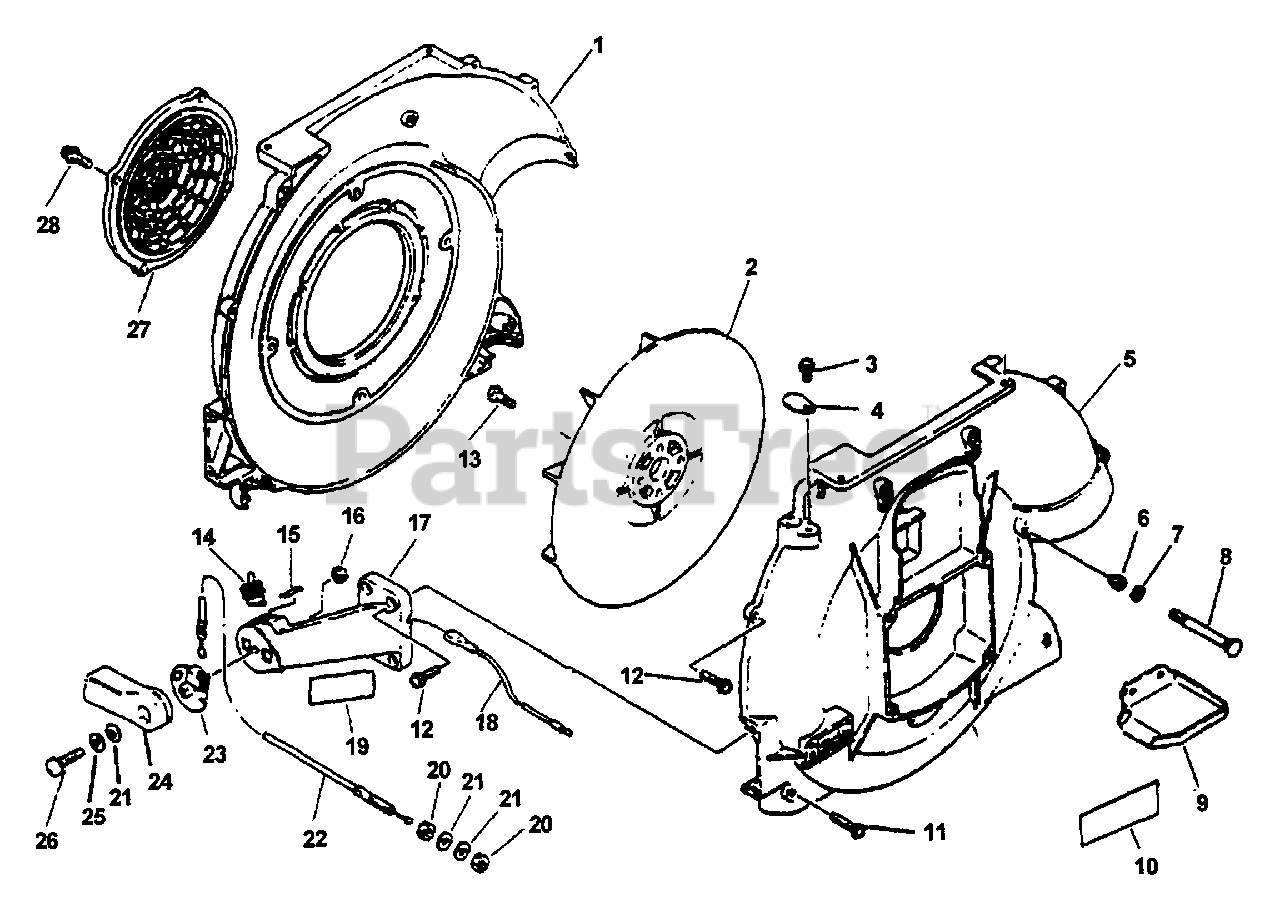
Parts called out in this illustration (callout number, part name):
1	COVER, FAN - INNER -- ORANGE
3	SCREW - 5X10
5	COVER, FAN - OUTER
6	NUT - 5 -- CAP
7	WASHER - 5
8	BOLT, ELBOW
9	BRACKET, MUFFLER COVER
10	LABEL - NOISE
11	SCREW - 5X25
12	SCREW - 5X20
13	BOLT - 5X16
14	IGNITION SWITCH ASSY
15	LABEL - STOP
16	LOCKNUT - 6
17	MOUNT, THROTTLE LEVER
19	LABEL - CAUTION
21	WASHER - 6
22	CABLE, THROTTLE
24	TRIGGER, THROTTLE
25	LOCKWASHER - 6
26	SCREW - 6X25
27	GUARD, DEBRIS
28	BOLT - 6X14
